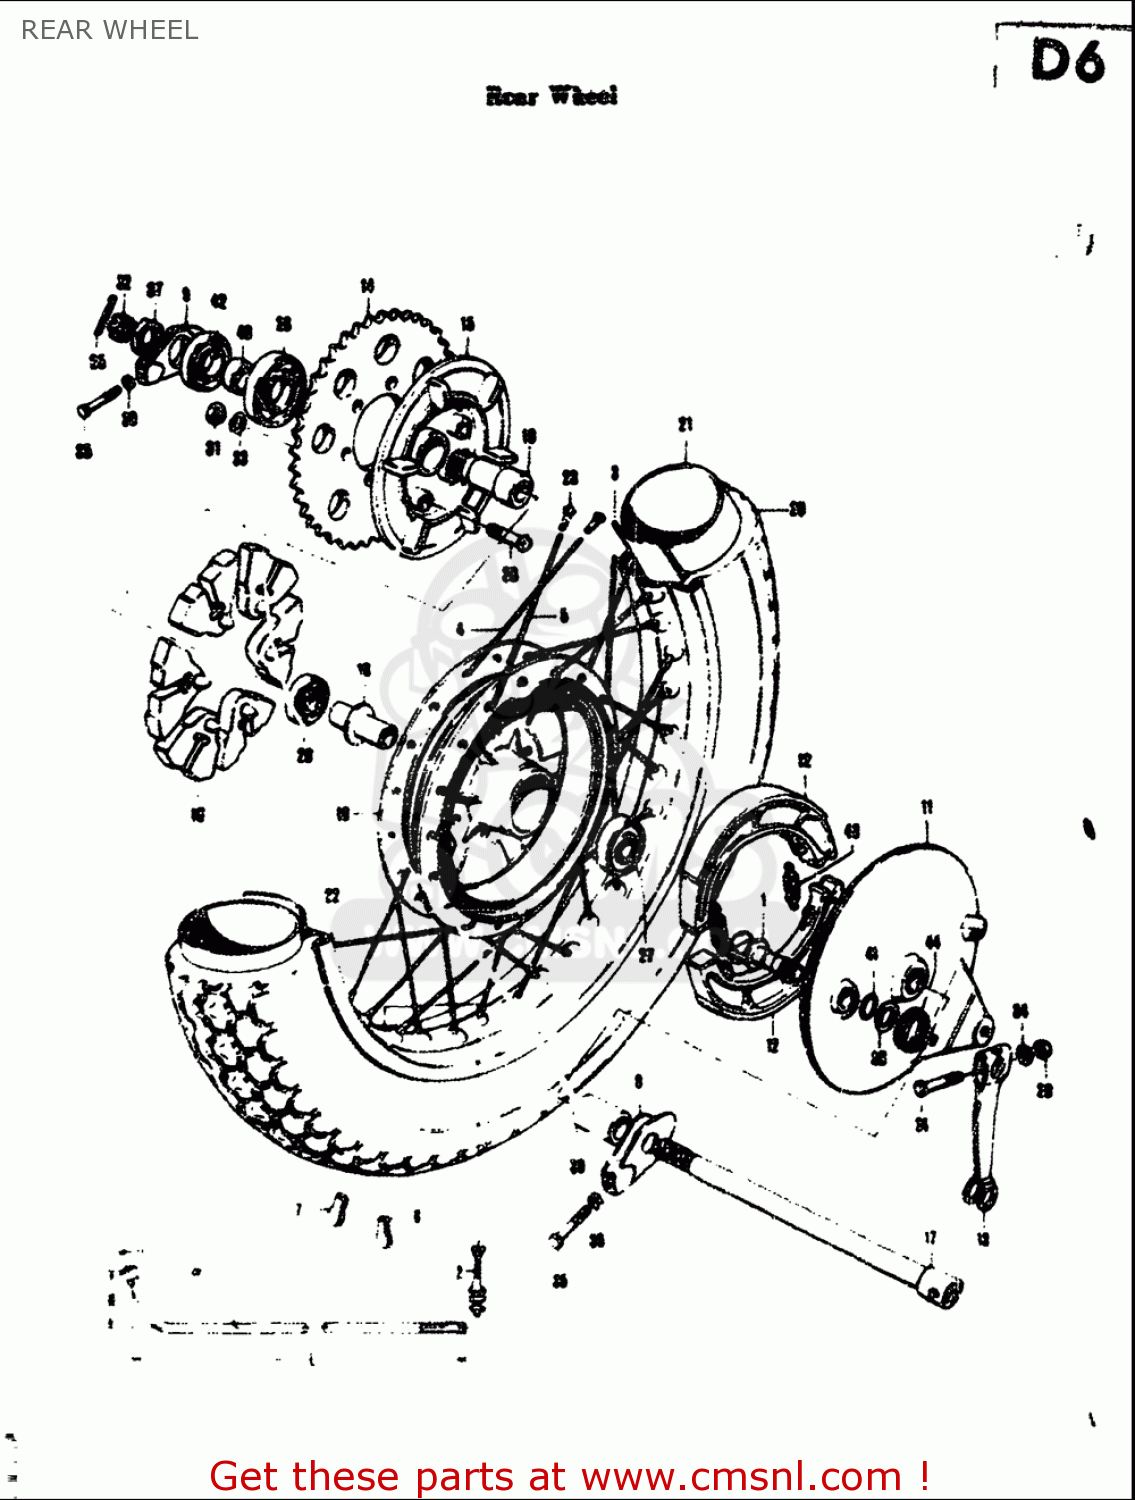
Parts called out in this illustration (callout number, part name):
3	PROTECTOR,INNER TUBE
6	BALANCER,WHEEL (B)
7	BALANCER,WHEEL (30G)
12	SHOE SET,BRAKE (NAS)
16	ABSORBER,RR HUB SHOCK
18	SPACER
21	TUBE ASSY,INNER
22	RIM,RR WHEEL
24	BOLT
26	BEARING(25X62X17)
27	BEARING
28	BEARING
29	NUT
30	NUT
31	NUT
33	WASHER,LOCK
34	WASHER
36	BOLT(10X35.5)
37	NUT
38	WASHER(15.5X24X1.6)
40	SPACER (25X30.5X11.3)
41	O RING(D:2.4,ID:14.8)
42	SEAL,OIL(30.5X52X8)
44	SPRING
